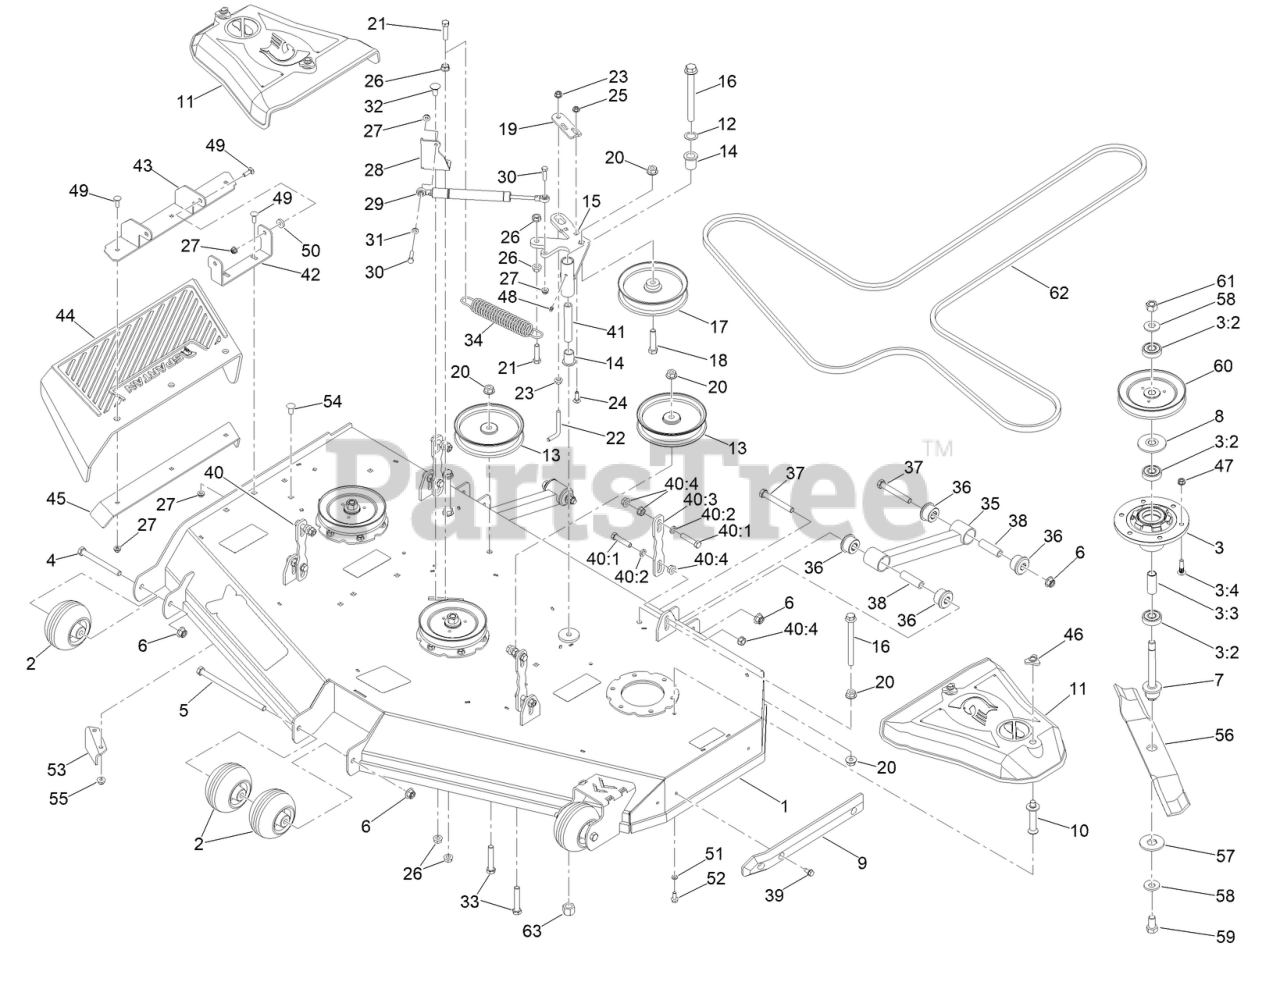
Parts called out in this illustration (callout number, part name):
1	ASM- 60" DECK W/DECALS
2	MWR ANTI-SCALP WHL W/O GREASE FITTING
3	SPINDLE ASM 5IN DECK
3:2	BEARING
3:3	SPACER, BEARING
3:4	BOLT-ROUND HEAD
4	SCREW-HH
5	1/2-13 X 8-1/2 HEX C/S GR 2 ZINC YELLOW
6	NUT-LOCK
7	SHAFT - SPINDLE
8	GUARD-BEARING TOP 0.673IN
9	MWR NYLON DECK GUARD
10	PIN-BELT COVER
11	COVER-BELT
12	.767IDX1.125ODX.016 THK TRIP WV WASHER
13	6-3/4IN IDLER PULLEY 15/16IN SPACER ASSY
14	3/4IN ID X15/16IN OD X 1-1/8IN FLNG BUSH
15	MWR DECK IDLER PULLEY ARM ASSY PAINT
16	1/2-13 X 5-1/2 HEX FLANGE BOLT GR 8 ZY
17	6-3/4IN IDLER PULLEY 7/16IN SPACER ASM
18	SCREW-HH
19	DECK IDLER PULLEY BELT RETNR BRKT PAINT
20	NUT-HHF
21	SCREW-HH
22	BOLT-L
23	3/8-16 HEX FLANGE NUT W/SERR ZINC YELLOW
24	BOLT-CARR
26	NUT-HF
27	NUT-HF, NI
28	DECK BELT IDLER DAMPER MTG BRKT PAINTED
29	IDLER GAS SPRING
30	SCREW-HH
31	.312IDX.625ODX.062 THK THRUST BRG OI BRZ
32	SCREW-CARR
33	1/2-13 X 2-3/4 HEX FLANGE BOLT (GR.8) YZ
34	MWR DECK SPRING
35	RZ MWR DECK STABLZR ASSY
36	RED A80 SUSP BUSHING
37	1/2-13 X 3-3/4 HEX C/S (GR.5) ZC/YEL
38	UTV A-ARM BUSHING SLEEVE
39	SCREW-HWH, THREAD CUT
40	RZ MWR DECK LINK ASM
40:1	SCREW-HH
40:2	.443 ID X .749 OD X .125 THK NYLON BLACK
40:3	RZ MWR DECK ACTUATOR CONN LINK PAINT
40:4	NUT-HF
41	MWR INNER IDLER SPACER
42	BRACKET-CHUTE
43	DECK CHUTE HINGE ASM
44	RZ MWR RUBBER DISCHARGE CHUTE
45	MWR DECK CHUTE HINGE BACKER BRKT
46	NUT-KNOB
48	1/4IN DRIVE TYPE GREASE FITTING YZ
49	5/16-18 X 1 CARRIAGE BOLT GR 8 YZ
50	.312 ID X .875OD X .1875 THK F/W NYL
51	WASHER-LOCK
52	SCREW-HHF
53	BAFFLE-DISCHARGE
54	SCREW-CARR
55	NUT-HF, NI
56	BLADE-ROTARY
57	WASHER-HEX
58	M16 SPRING WASHER (39MMOD/ 3.9MM THK)
59	M16X1.5-30MM C10.9 HEX BOLT
60	PULLEY
61	M16X1.5 C8.8 HEX NUT
62	BELT-V
63	NUT-LOCK, NI
